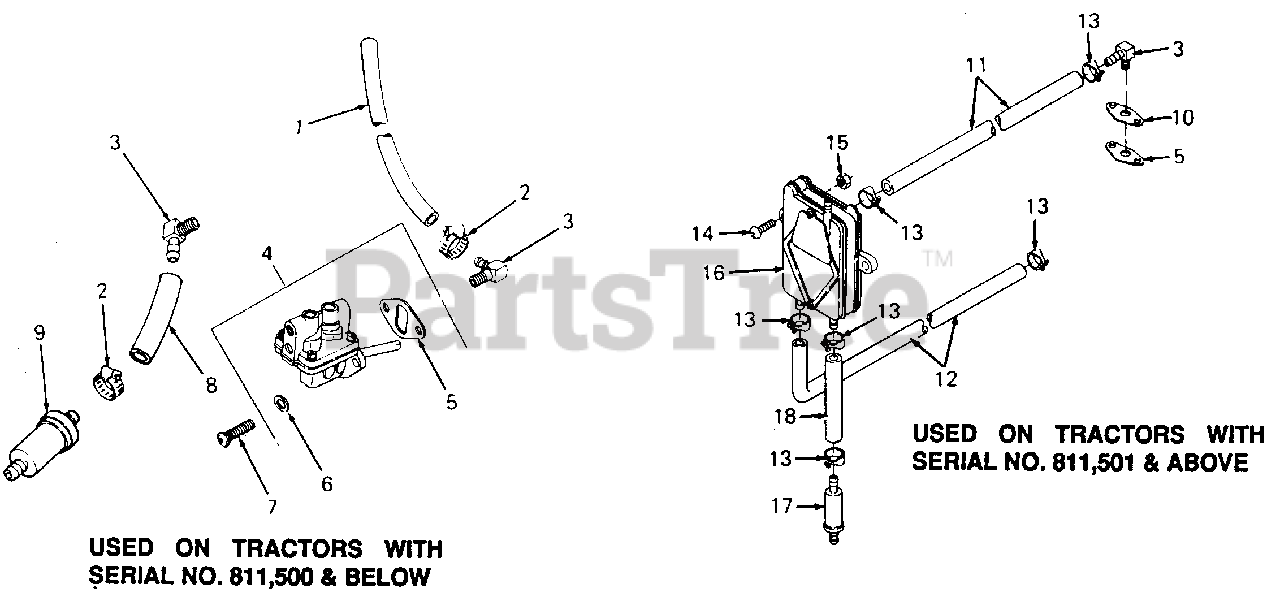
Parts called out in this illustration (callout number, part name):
1	Line, Fuel
2	Clamp, Hose
3	Connector, Hose
4	Pump Fuel
5	Gasket, Fuel Pump
6	Washer, Plain, 1/4
7	Screw, Pozidriv TH, 1/4-20 X .62 Lg
8	Line, Fuel
9	Filter, Fuel
10	Cover
11	Line, Fuel (Short)
12	Line, Fuel (Long)
13	Clamp, Hose
14	Screw, Truss Mach, 10-24 X .62
15	Nut, Hex Center Lock, 10-24
16	Pump, Fuel
17	Filter, Fuel
18	Line, Fuel, 5" Lg
